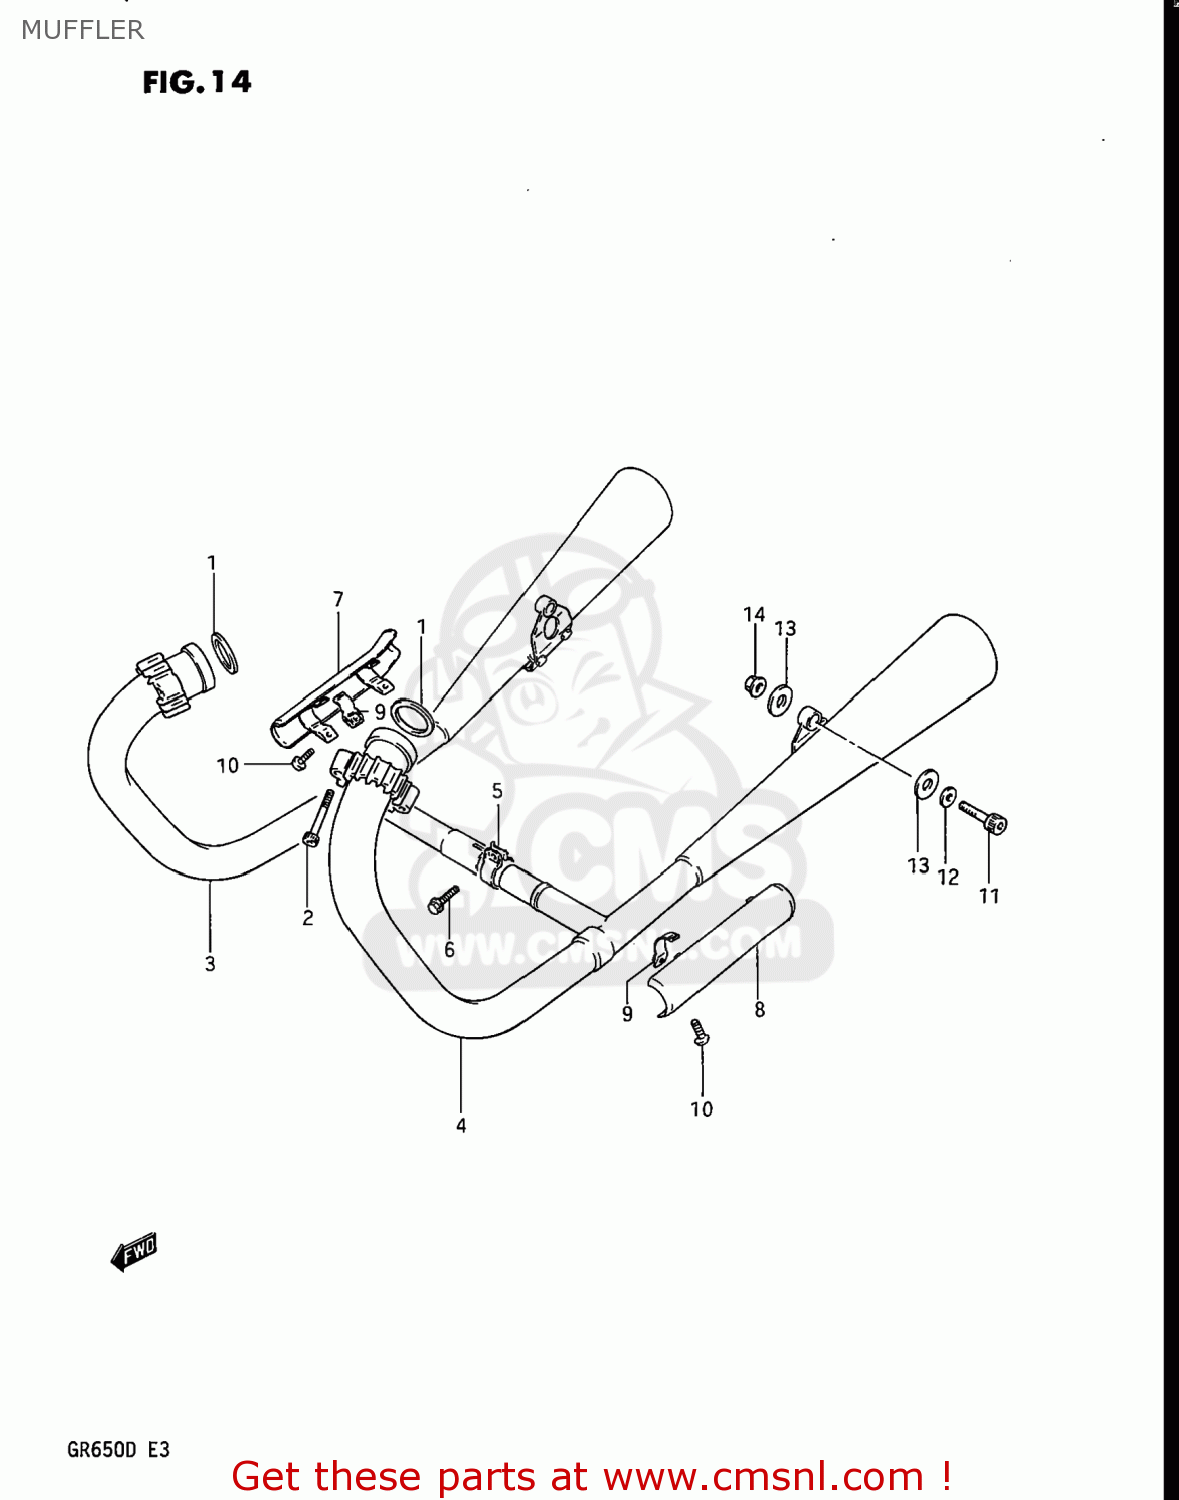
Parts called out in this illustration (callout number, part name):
1	GASKET,EXHAUST PIPE (NAS)
2	BOLT
3	MUFFLER ASSEMBLY,RIGHT
4	MUFFLER ASSEMBLY,LEFT
5	CLAMP,EXHAUST
6	BOLT
7	COVER,MUFFLER,RIGHT
8	COVER,MUFFLER,LEFT
9	CLAMP,MUFFLER COVER
10	SCREW
11	BOLT
12	WASHER
13	WASHER(10.5X22X2.3)
14	NUT
